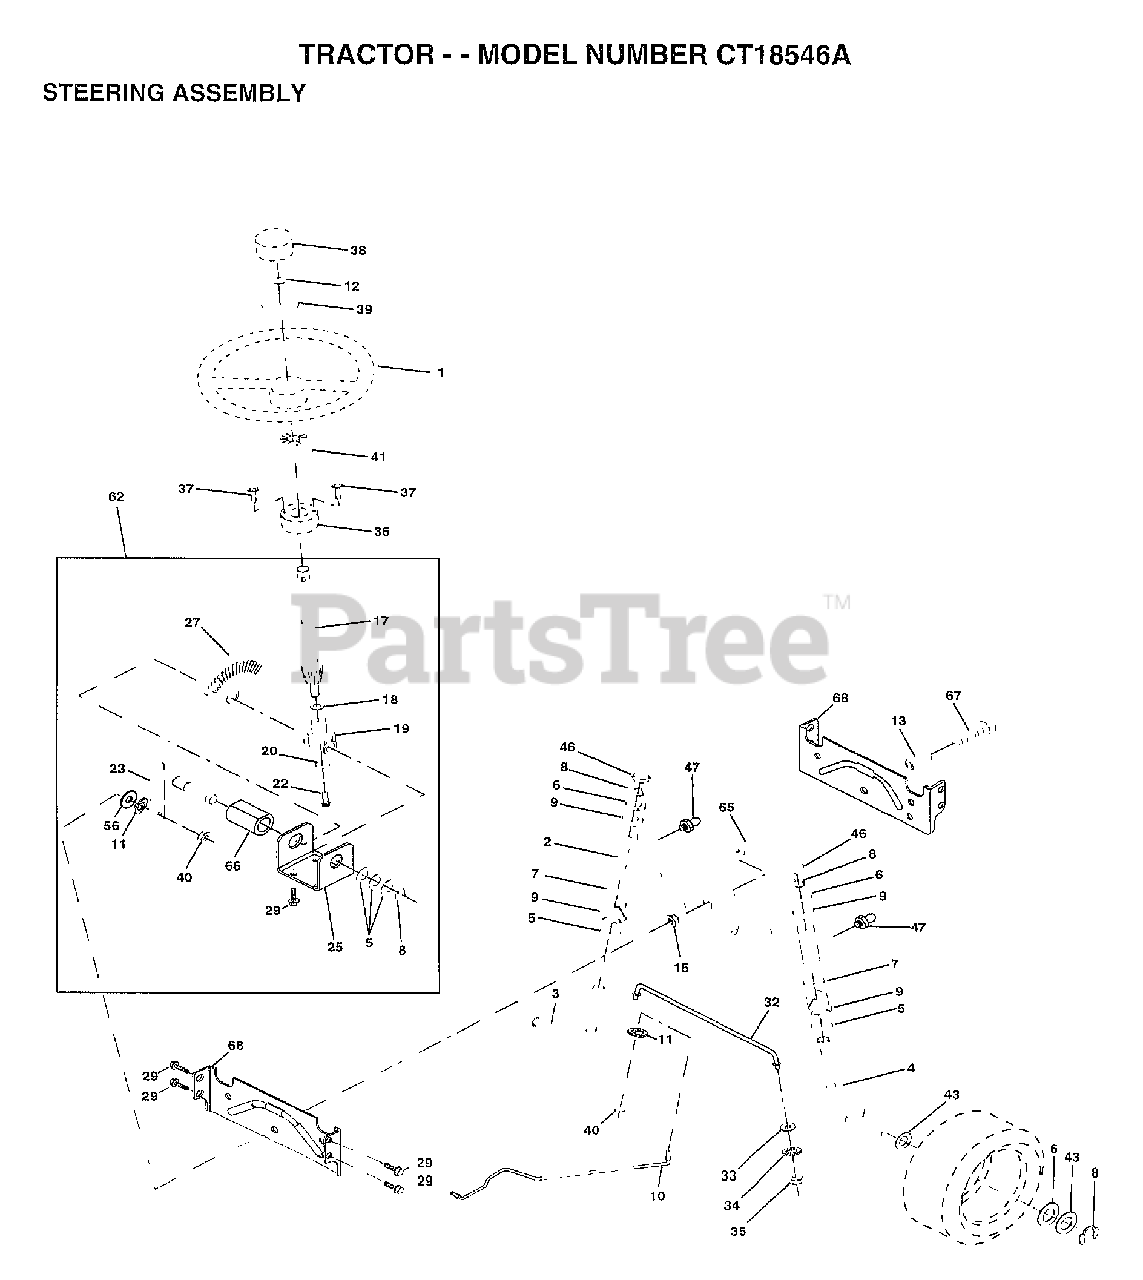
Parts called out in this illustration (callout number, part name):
1	WHEEL STR AYP BLK
2	AXLE ASM
3	"SPINDLE ASM, LH"
4	SPINDLE ASM RH
5	WASHER .T
6	WASHER
7	WASHER
8	RING
9	COL. SRTG. BEAR.
10	DRAGLINK-STAMPED
11	LOCKWASHER
13	BEARING AXLE
15	"NUT-LOC,FLANGE LT"
17	STEERING SHAFT
18	THRUST WASHER
19	SUPPORT.SHAFT
22	SCREW HEX SOC1/4-
25	BRKT-STEERING
27	GEAR SECTOR
29	SCREW
32	ROD.TIE.19.75
33	WASHER M
34	LOCKWASHER
35	NUT.LOCK.5/16-24
36	BUSHING.STRG.3/4
37	"SCREW-TT,10-32 FL"
38	CAP STEER AYP
39	WASHER
40	GRIPCO NUT
41	ADAPTER LT
43	WASHER
46	CAP
47	ZERK M
62	STEERING KIT
65	SPACER AXLE
66	"BEARING-ARM,PITMA"
67	BOLT
68	MANUAL.P.EN12536B
